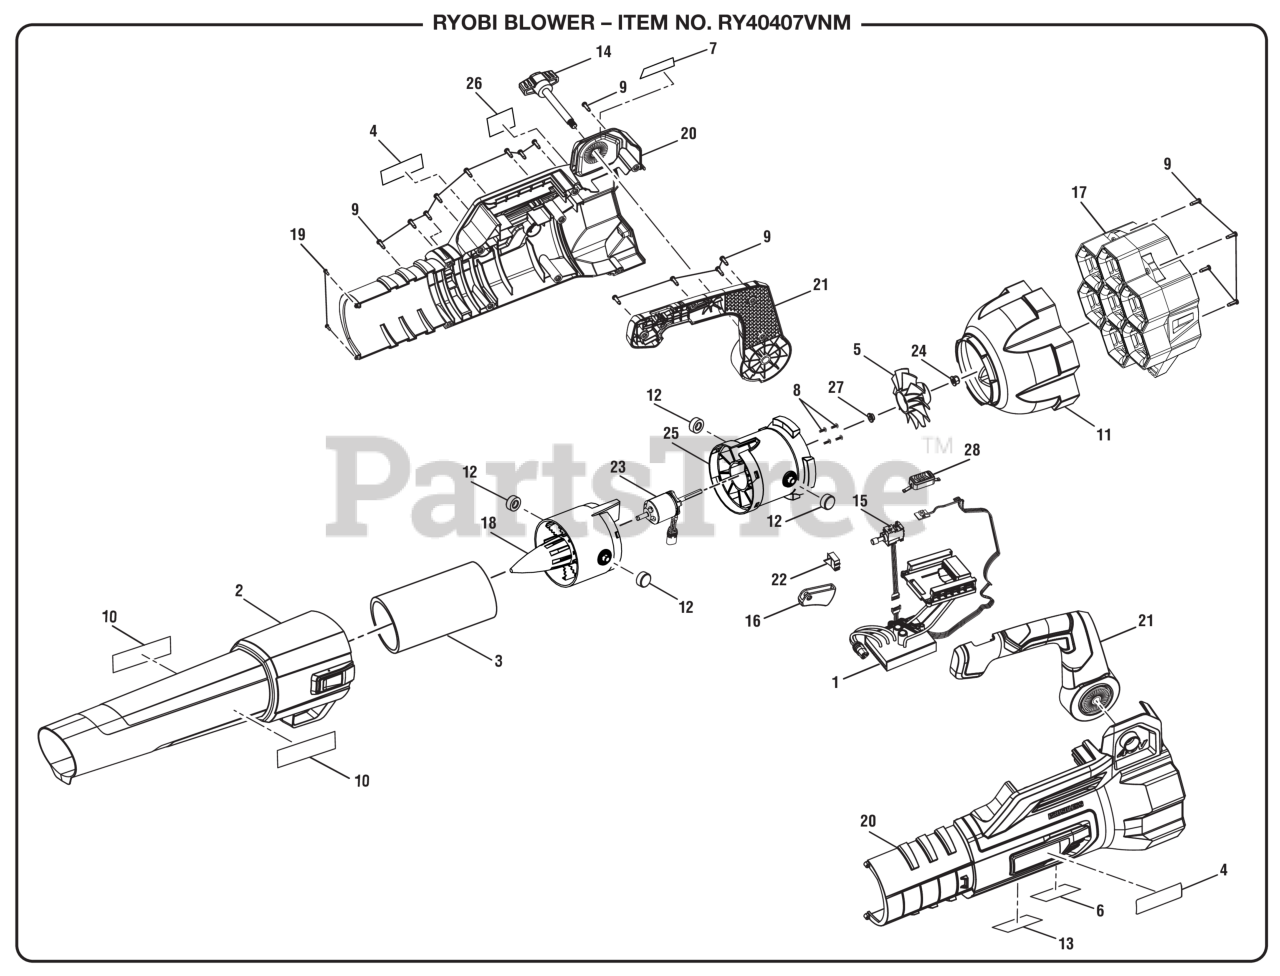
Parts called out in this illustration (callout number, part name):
1	Motor Controller and Battery Connection Assembly
2	Blower Tube Assembly (Includes Key No 10)
3	Sound Dampening Foam
4	Logo Label
6	Warning Label (French and Spanish)
7	Warning Icons Label
8	SCREW, M3.0X0.5-6h PWH PHILIPS B \ L=8MM
9	Screw (M4 x 14 mm, T15 Torx Pan Hd.))
10	Whisper Series Label
11	Inlet Bell Assembly
12	Rubber Cap
13	Data Label
14	Handle Knob
15	Variable Speed Switch
17	Inlet Cover Assembly
19	Screw (M3 x 8 mm, Pan Hd., Pan Hd)
20	Housing Assembly (Includes Key Nos 4, 6-7, 13 and 26)
21	Handle Assembly
22	Switch Cap
24	Flange Lock Nut (M6 x 1 mm)
25	Motor Mount
26	Warning and Warning Icons Label (English)
28	Turbo Button
